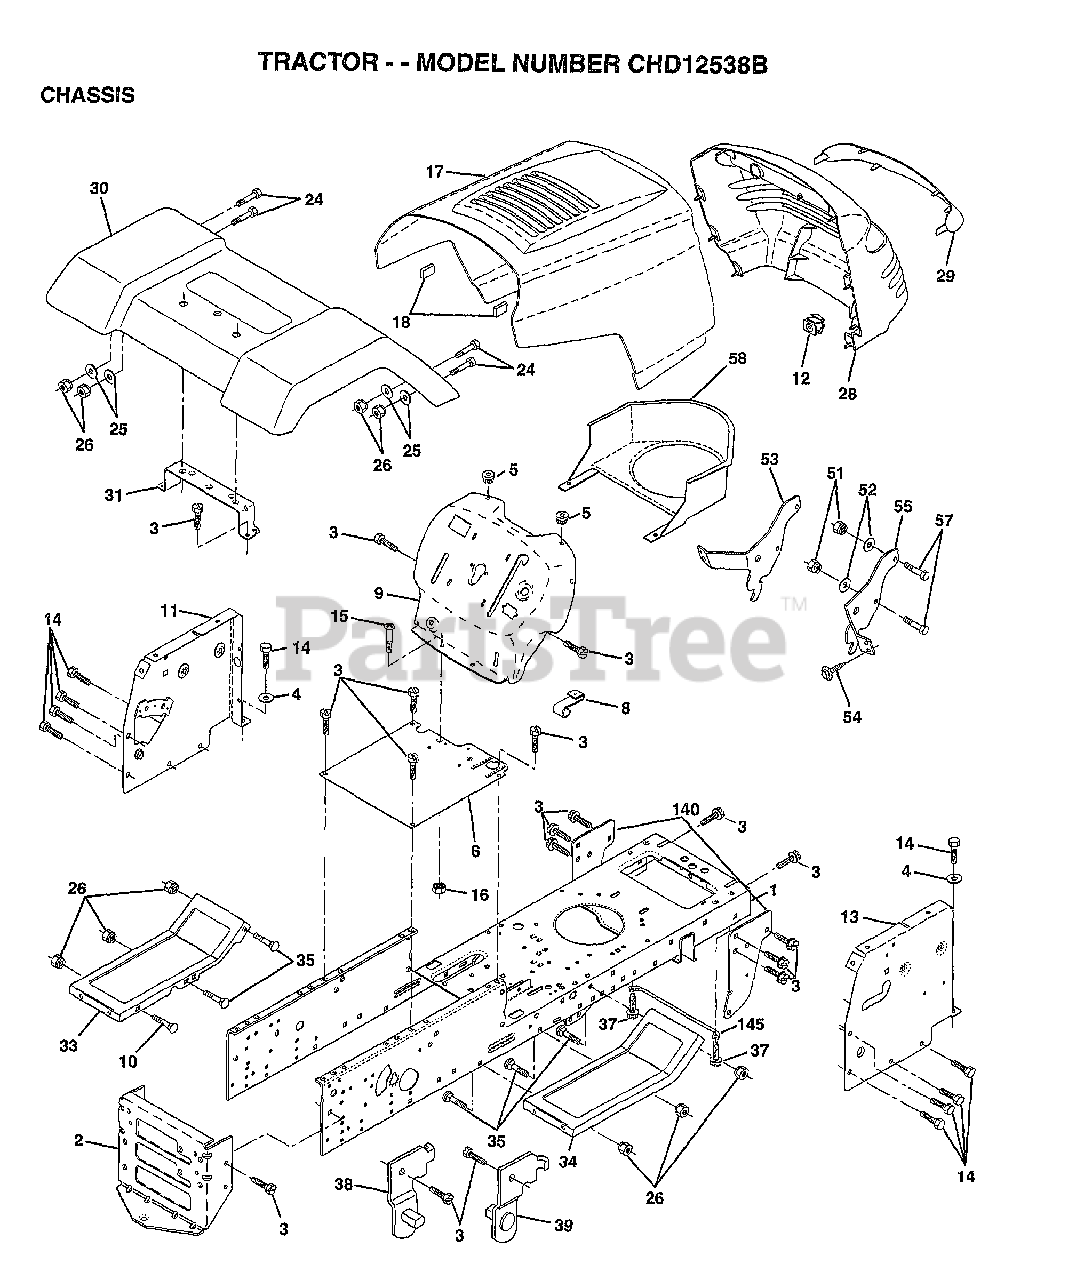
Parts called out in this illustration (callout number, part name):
3	SCREW
4	WASHER
5	BUMPER-HOOD/DASH
6	"SADDLE-SLKSCR,5SP"
8	CLIP.RETAINER
9	DASH SILKSCREEN
11	"PANEL-DASH,LH"
12	CLIP.TINNERMAN
14	SCREW LT
15	SCREW
17	HOOD.STEEL.ASSY
24	BOLT
25	WASHER
26	NUT
28	GRILLE
29	LENS QUADRA
30	FENDER PNT LT
31	BRKT FENDER
33	FOOTREST.LH.PERF.
34	FOOTREST.RH.PERF.
35	BOLT
38	BRACKET ASM LH
39	BRACKET ASM RH
51	NUT
52	WASHER
53	BRACKET.GRILLE.LH
54	SCREW.HEX.WS.HD
55	BRACKET.GRILLE.RH
58	AIR DUCT
140	BRKT SUSPENSION
145	"ROD POVOT,CHASSIS"
